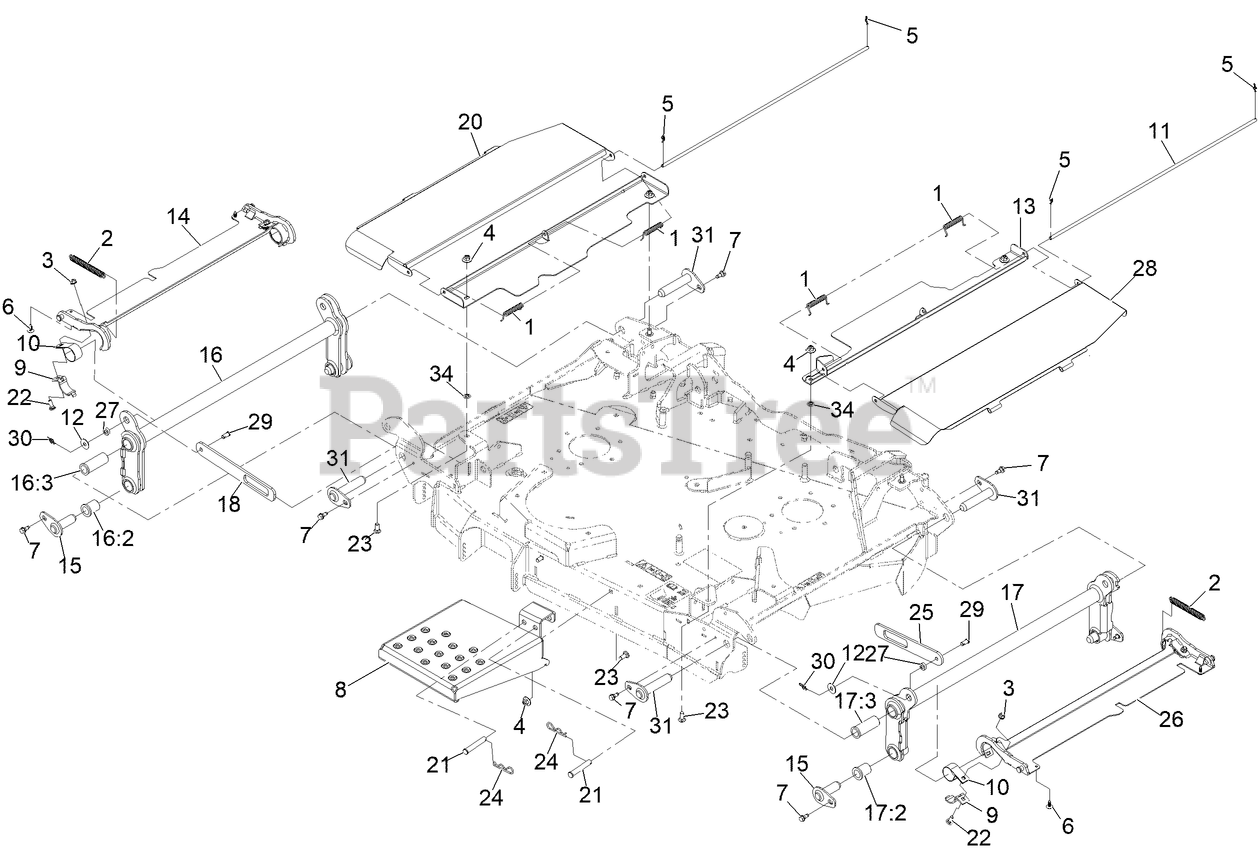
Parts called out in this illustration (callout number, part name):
1	SPRING-TORSION
3	NUT-HF, NI
4	Nut-Nyloc 3/8-16 Flg
5	PIN-COTTER, LOCKING
6	PLUG-PLASTIC
7	SCREW-SHOULDER
8	PLATE-DECK STEP
9	PLATE-RETAINER, BEARING
10	BEARING-STRAP, NYLON
11	COVER-ROD, PIVOT
13	SHIELD-CENTER, LH
14	SHIELD-CENTER, RH
15	ASM-DECK PIN
16	ASM-RH FOLD ARM
16:2	BUSHING-FLANGED
16:3	BUSHING-FLANGE
17	ASM-LH FOLD ARM
17:2	BUSHING-FLANGED
17:3	BUSHING-FLANGE
18	STRAP-RH FLAG
20	Panel-Shield Hinge, LH
21	PIN-CLEVIS
22	SCREW-CARR
23	BOLT-CARR
24	PIN-HAIR
25	STRAP-LH FLAG
26	ASM-WING COVER, [RED]
27	BUSHING
28	Shield-Center, RH
29	PIN-CLEVIS
30	PIN-COTTER, LOCKING
31	ASM-DECK PIN
34	NUT-PUSH
